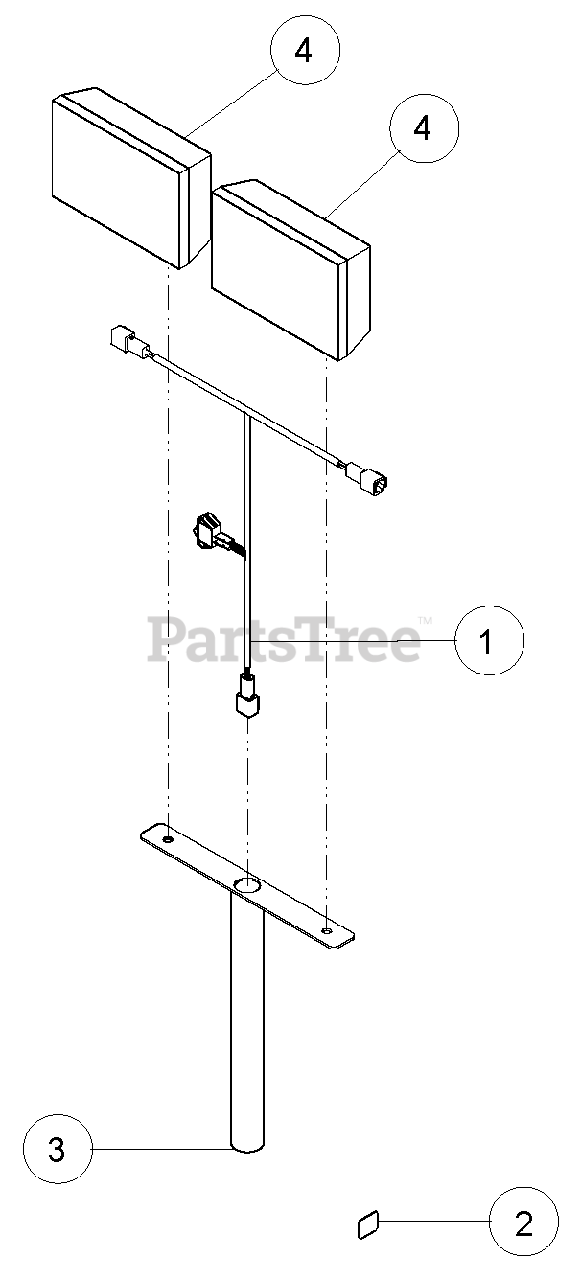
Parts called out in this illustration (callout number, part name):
1	HARNESS, DEUTSCH DT04-2P TO DT04-2P
2	DECAL, LIGHTS
3	WELDMENT, LIGHT MOUNT
4	LAMP, 4 X 6 HALOGEN W DEUTSCH
